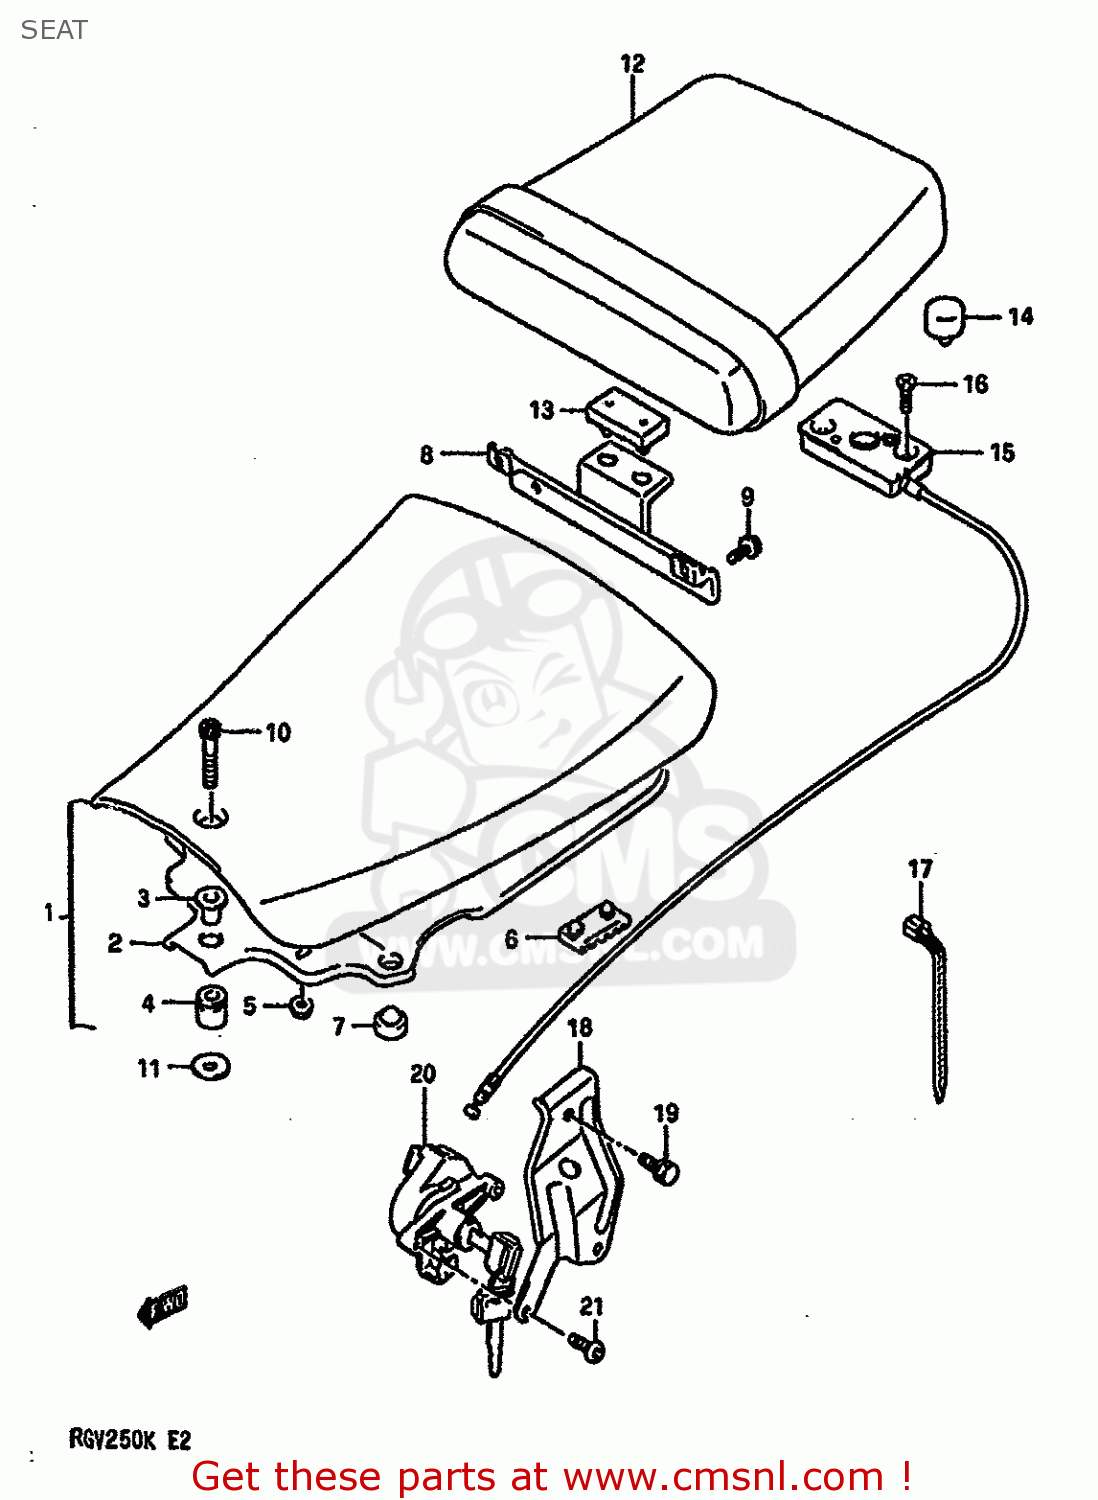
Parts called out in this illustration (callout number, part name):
1	SEAT ASSY (BLACK)
2	FRAME,SEAT BOTTOM
3	COLLAR,FR
4	CUSHION
5	NUT
6	CUSHION,SEAT(40X20X6)
7	CUSHION
8	BRACKET,SEAT SUPPORT FRONT
9	BOLT
10	BOLT
12	SEAT ASSY,PILLION (BLUE)
13	CUSHION
14	CUSHION
15	BRACKET,SEAT SUPPORT REAR
16	SCREW
17	CLAMP(L:125)
18	BRACKET,SEAT/HELMET
19	BOLT
20	LOCK ASSY,SEAT/HELMET
21	SCREW(6X20)
